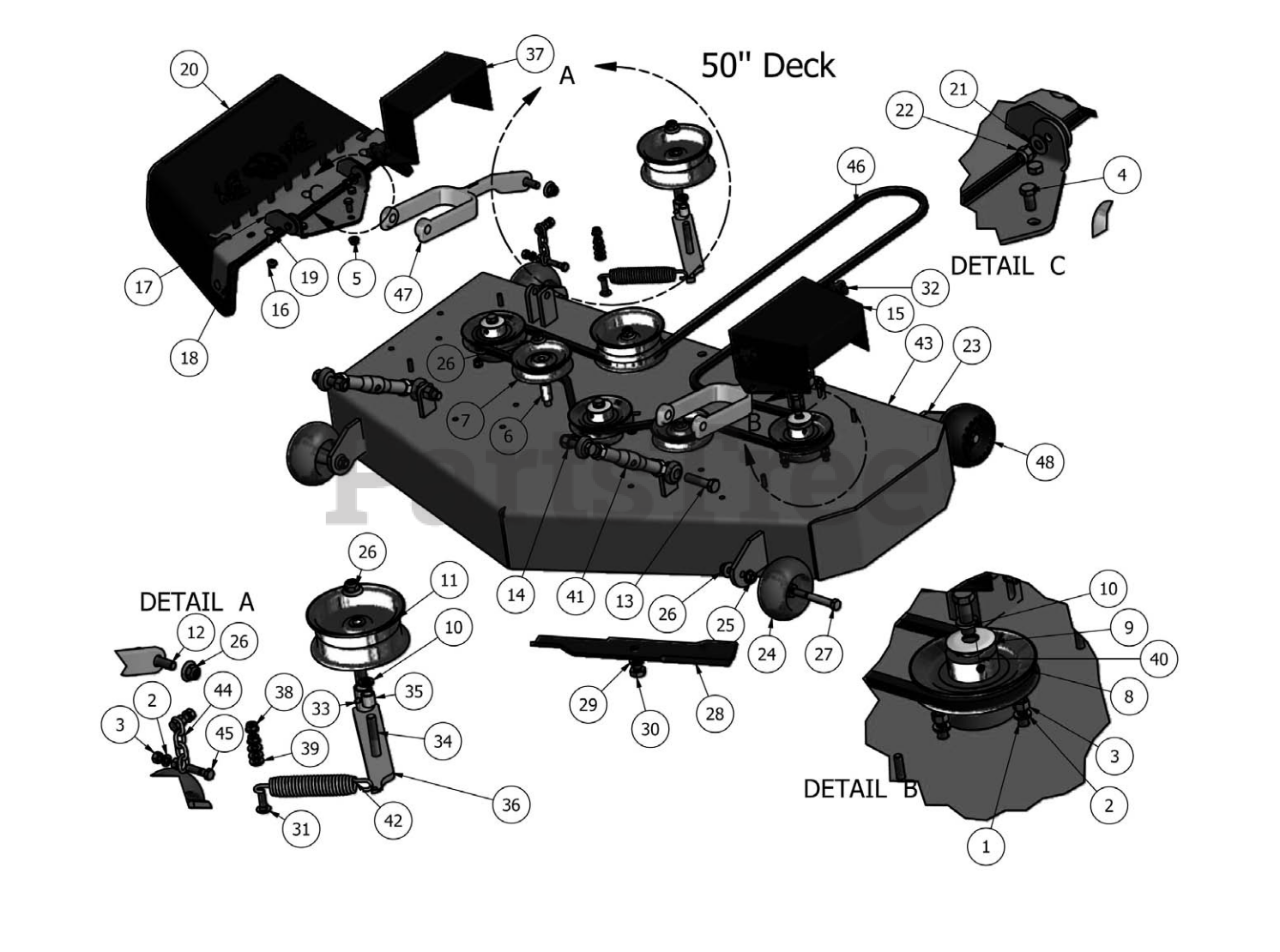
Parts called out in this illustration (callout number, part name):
1	3/8" x 1 1/4" Hex Bolt
2	3/8" Lock Washer
3	3/8" Hex Nut
4	3/8" x 3/4" Hex Bolt
5	3/8" Flange Nut
6	Pulley Spacer
7	4 3/4" Idler Pulley
8	5" Deck Pulley
9	Cup Washer
10	1/2" Lock Washer
11	5 3/4" Deck Idler Pulley
12	1/2" x 2 1/2" Hex Bolt
13	5/8" x 2 1/2" Hex Bolt
14	5/8 Std NC Nylock Nut
15	Metal Pulley Cover
16	5/16" Flange Nut
17	Discharge Chute Upper Hanger Plate
18	Rubber Discharge Chute (Assembly)
19	5/16" x 1 1/4" Carriage Bolt
20	Rubber Discharge Chute (Rubber Only)
21	.360 ID Plastic Washer
22	3/8 Nylock Nut
23	50" Complete Deck
24	Anti-Scalp Rollers (Roller Only)
25	1/2" Flange Nut
26	1/2-13 Nylon Flange Nut-Orange
27	1/2" x 4" Bolt (Grade 8)
28	50" ZT High Lift Fusion Blade
29	5/8" Lock Washer
30	5/8" x 1 1/2" Grade 8 Bolt
31	3/8" x 1 1/4" Carriage Bolt
32	5/16" Knob
33	1/4" Drive in Grease Fitting
34	1/2" x 3" Hex Bolt
35	3/4 OD x 1/2 ID x 3\4 Length
36	Deck Idler Arm
37	50"Spindle Cover Right Side
38	3/8" Nylock Flange Nut
39	3/8" Flat Washer
40	1/2"-20 × 1 1/2 - Grade 5 Fine Thread Bolt
41	Turnbuckle
42	Deck Idler Spring
43	50" Deck (Shell Only)
44	ZT Deck Hanger Assembly
45	3/8" x 1 1/2" Hex Bolt
46	50" ZT Deck Belt
48	Anti-Scalp Roller (Assembly)
